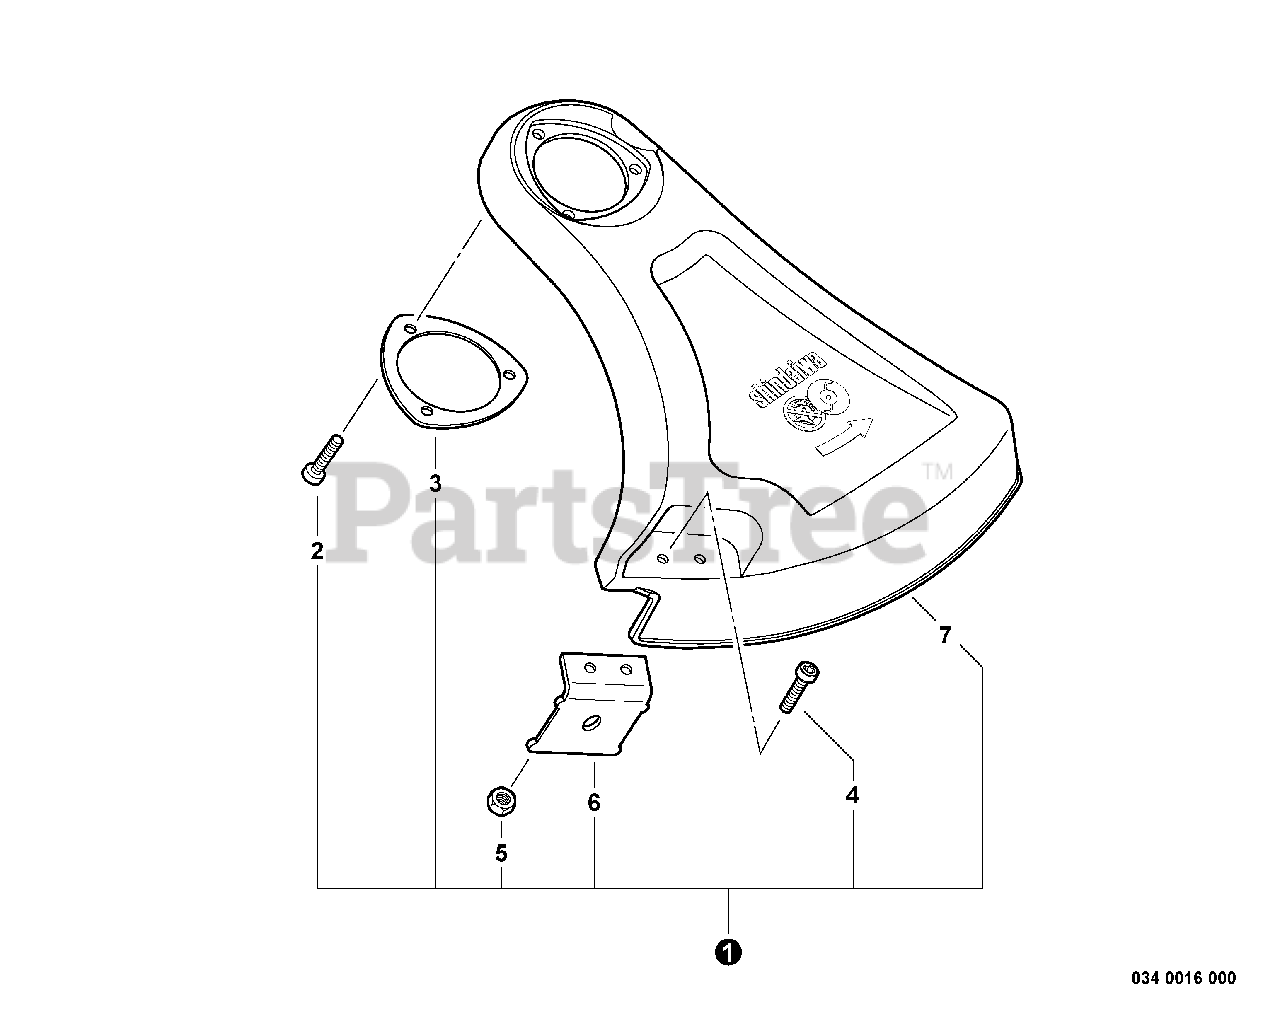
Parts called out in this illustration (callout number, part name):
1	DEBRIS SHIELD KIT
2	SCREW - 5X16
3	PLATE, SHIELD
4	SCREW - 5X12
6	KNIFE, TRIMMER LINE
7	SHIELD, DEBRIS
